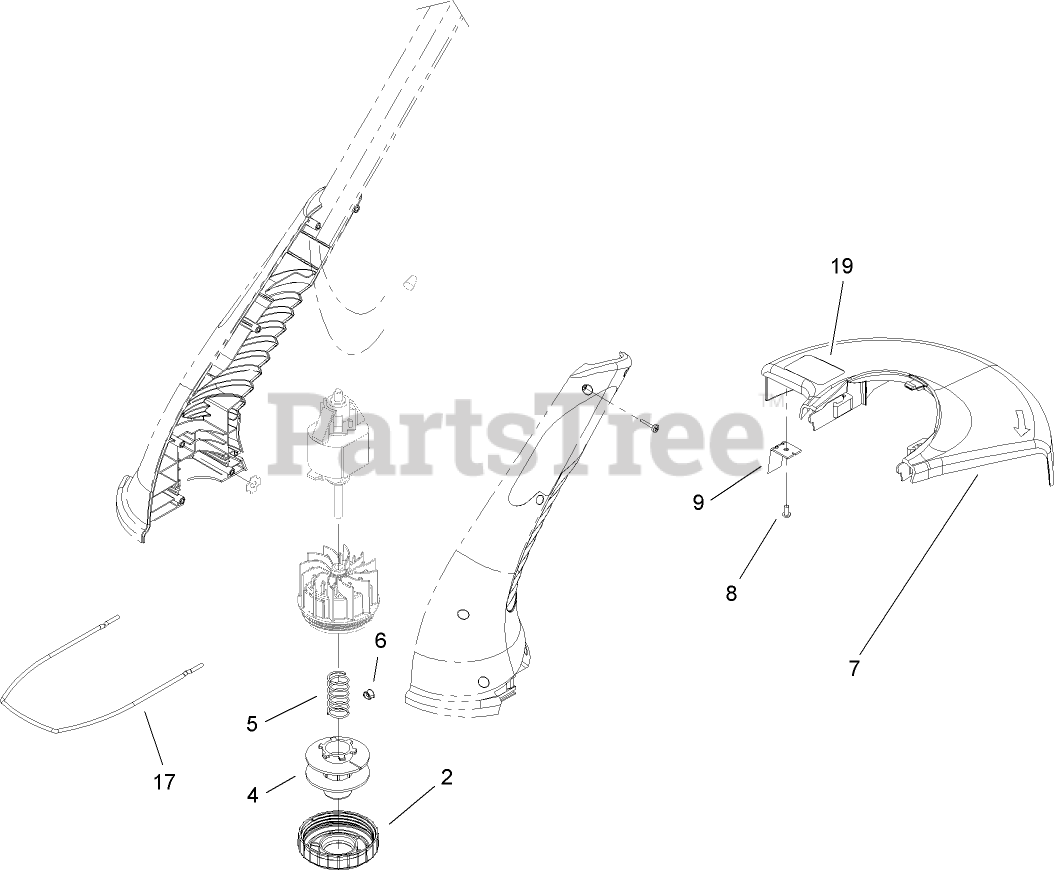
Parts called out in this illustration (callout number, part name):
2	CAP-DRUM
4	.065 SPOOL ASM
4:1	SPOOL-LARGE
5	SPRING-EXTENSION
6	EYELET-GUIDE
7	SHIELD-VARIABLE CUT
8	SCREW-PPH
9	BLADE-VARIABLE CUT
17	GUIDE-EDGE
19	DECAL-SHIELD, LENGTH
